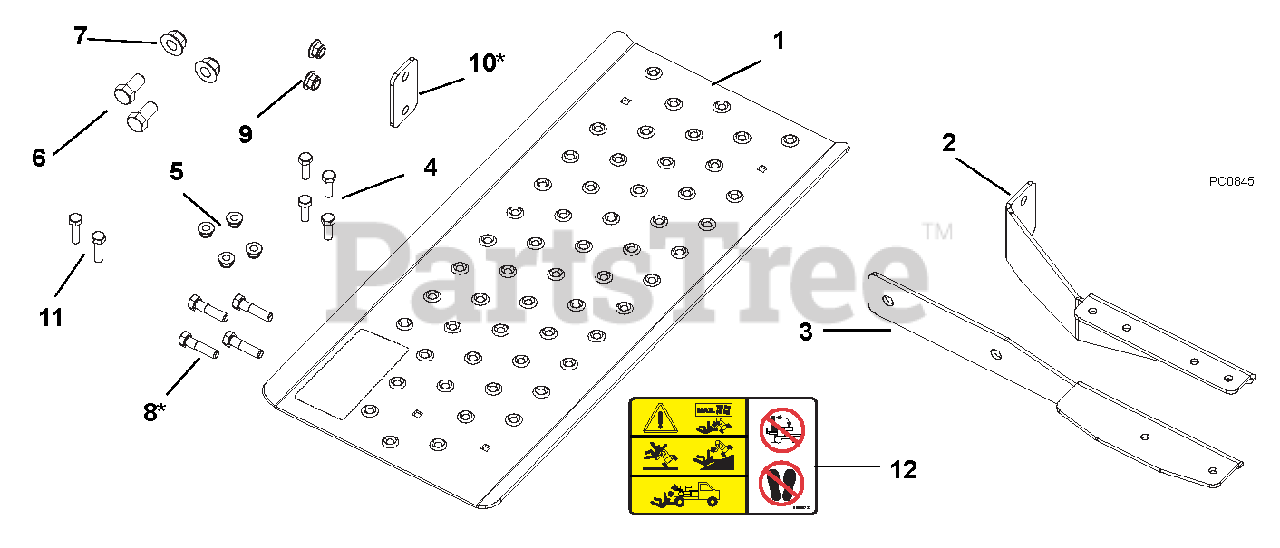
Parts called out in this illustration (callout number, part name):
1	BRKT, LOG SPLITTER WORK TABLE
2	BRKT, REAR TABLE MOUNT
3	BRKT, FRONT TABLE MOUNT
4	@BLT-RHDSSQNK .31-18X1.00 G5YZ
5	@NUT-LK-NYL-FLG .31-18 YWZC
6	@BLT-HEX .50-13X1.00 GR5 YWZC
7	@NUT-LK-TOP-FLG .50-13 YWZC
8	@BLT-HEX .38-16X1.50 GR5 YWZC
9	@NUT-LK-TOP-FLG .38-16 YWZC
10	PLATE, WORK TABLE SPACER
11	@BLT-HEX .38-16X1.25 GR5 YWZC
12	DECAL,SPLITTER TABLE
